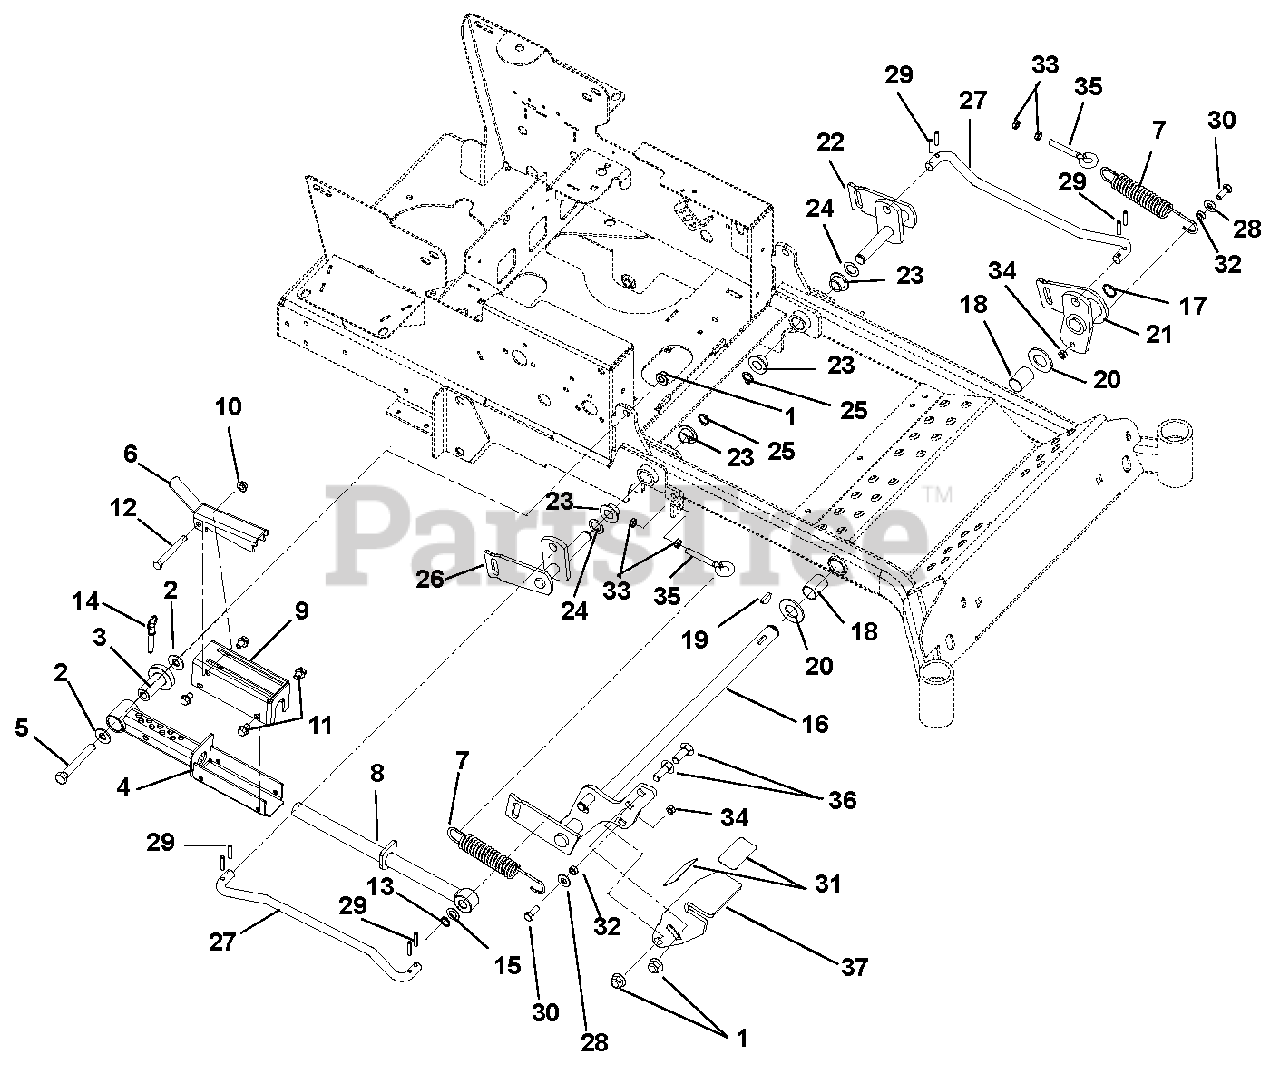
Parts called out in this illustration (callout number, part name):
1	Nut, Nyloc Top Flange .50-13
2	Washer, Flat Steel .531 x 1.25 x .10
3	Bearing, Pedestal
4	Weldment, Mechanical Lift
5	Bolt, Hex .50-13 x 3.75 Grade 5
6	Lock, Up, Mechanical Lift
7	Spring, Tension .162 x 1.25 x 8.25 Weldment 25
8	Weldment, Mechanical Lift Shaft
9	Weldment, Mechanical Lift Cover
10	Nut, Nyloc Flange 3/8-16
11	Screw, Tapping .38-16 x .50 Hex Washer Head
12	Bolt, Hex .38-16 x 3.25 Grade 5
13	Ring, Retaining External .625 x .050
14	Pin, Spring Ball .375 O.D. x 1.50
15	Washer, Flat Steel .630 x 1.005 x .062
16	Deck Lift
17	Ring, Retaining External 1.00 x .078
18	Bushing 1.00 ID x 1.125 OD x 1.50
19	Key, Woodruff .25 x 1.00
20	Washer, Flat Steel 1.062 x 2.0 x .134
21	Weldment, Left Hand Mower Lift Arm
22	Weldment, Left Hand Rear Mower Lift Arm
23	Bushing, Flange Nylon .762 x 1.0 x .580 x 1.48
24	Washer, Hardened Steel .758 x 1.23 x .031
25	Ring, Retaining External .689 x .077
26	Weldment, Right Hand Rear Mower Lift Arm
27	Rod, Lift Assist
28	Washer, Flat Steel .438 x 1.00 x .083
29	Pin, Roll .25 x 1.25 Stainless Steel
30	Bolt, Hex .38-16 x 1.00 Grade 5
31	Grip, Pedal
32	Bushing, Sleeve .377 x .624 x .235
33	Nut, Hex, Jam .375-16
34	Nut, Locking, Jam, Center .375-16
35	Bolt, Eye .375-16 x 2.50
36	Bolt, Round Hd.Square Neck .50-13 x 1.50 Grade 5 YZ
37	Foot Pedal, Adjustable Black
